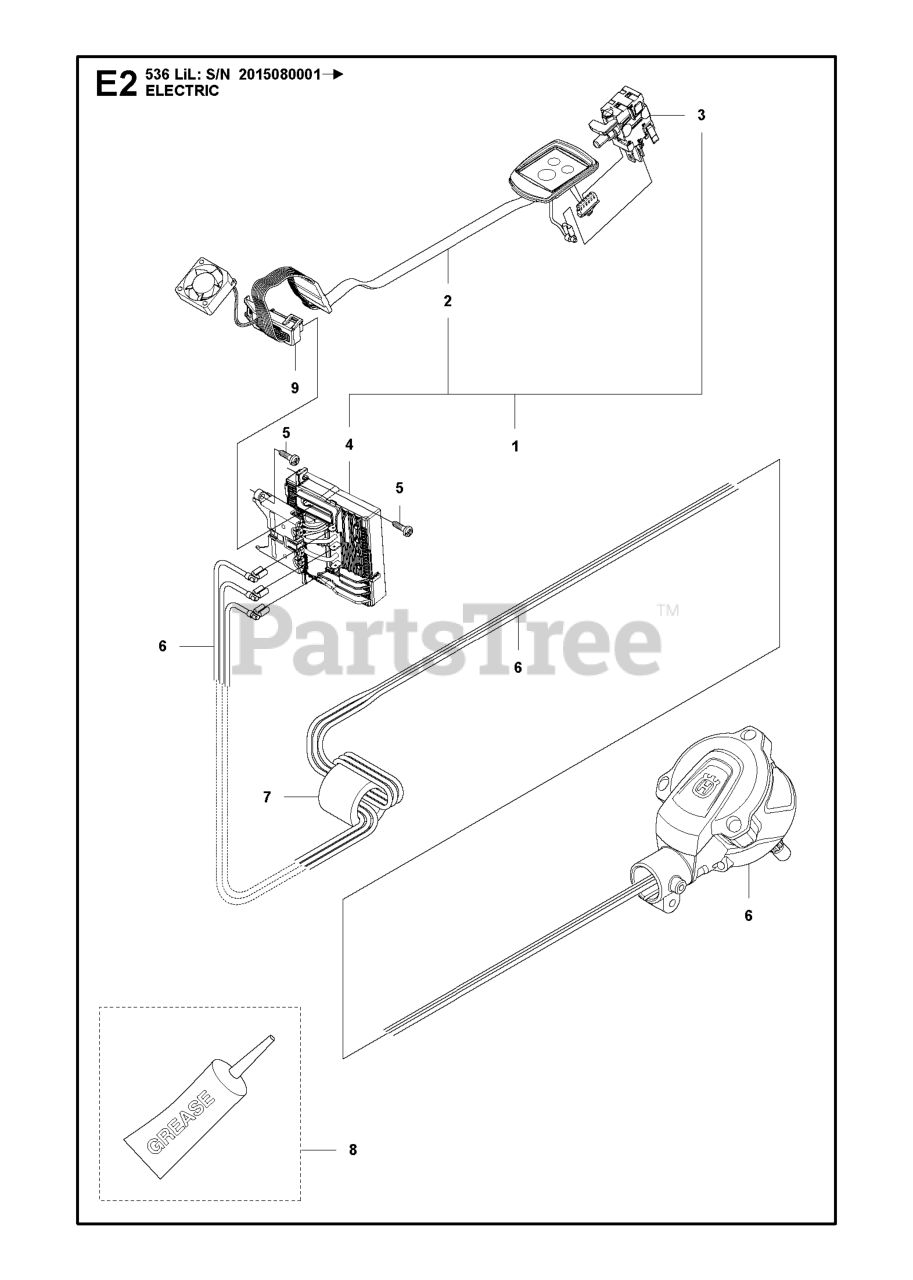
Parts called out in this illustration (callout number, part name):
1	CONTROL UNIT
2	WIRING ASSY
3	TRIGGER SWITCH
4	CONTROL UNIT
7	FERRITE CORE
8	GREASE TUBE Q8 RUYSDAEL WR2
